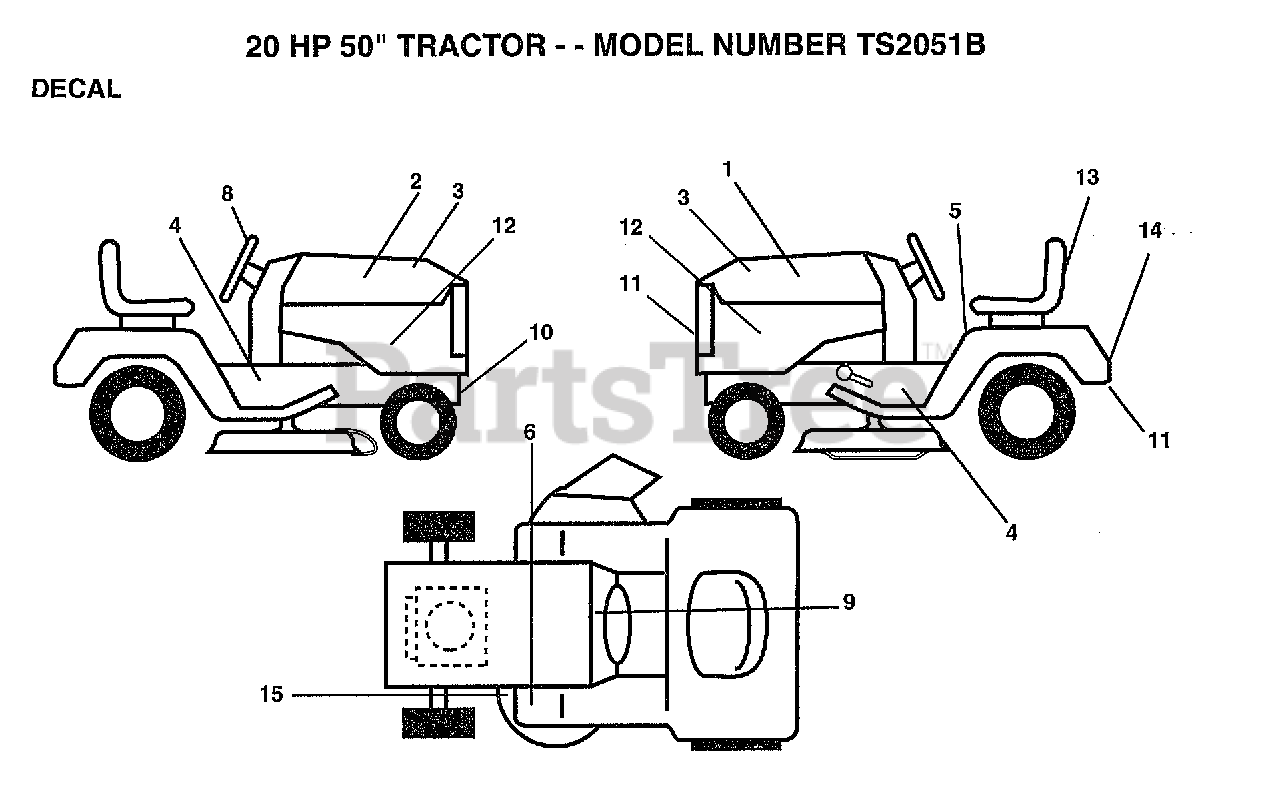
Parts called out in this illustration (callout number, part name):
5	DECAL
8	DECAL.STRG.WHL
9	DECAL.DASH.INST.
11	PLATE.NAME.SMALL
12	DECAL.PANEL.SIDE
13	DECAL.SEAT.AM.FLG
